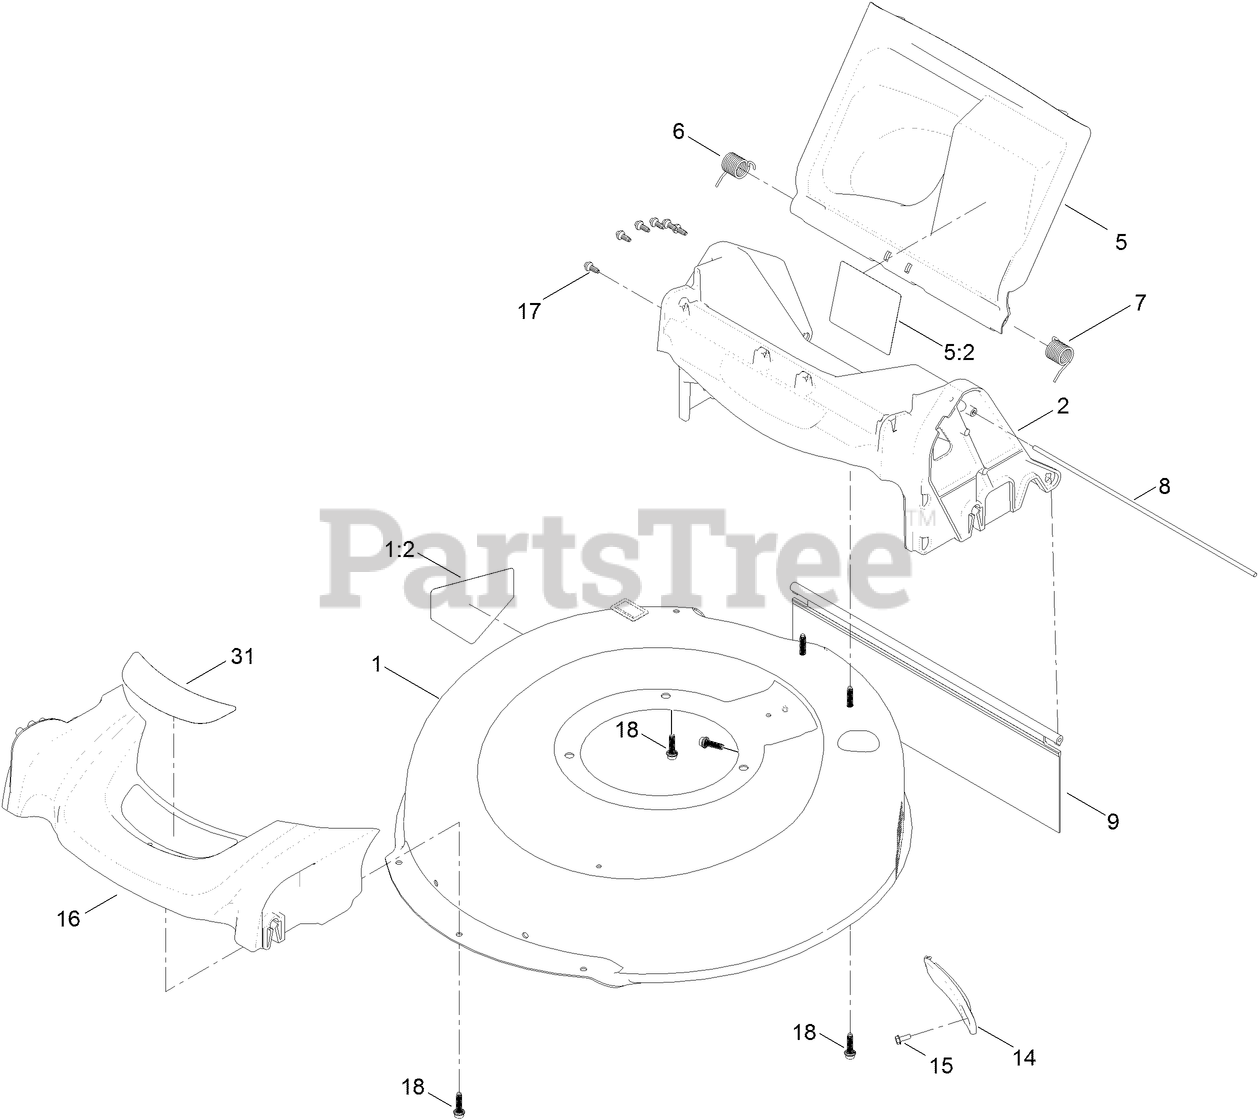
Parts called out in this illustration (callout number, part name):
1:2	DECAL-DANGER
2	CHUTE ASM
5	REAR DEFLECTOR ASM
5:2	DECAL-WARNING
6	SPRING-TORSION
7	SPRING-TORSION
9	SHIELD-TRAILING
14	COVER-BELT
15	SCREW-TAPTITE
18	SCREW-FLANGE, PLASTIC
31	DECAL-DECK
